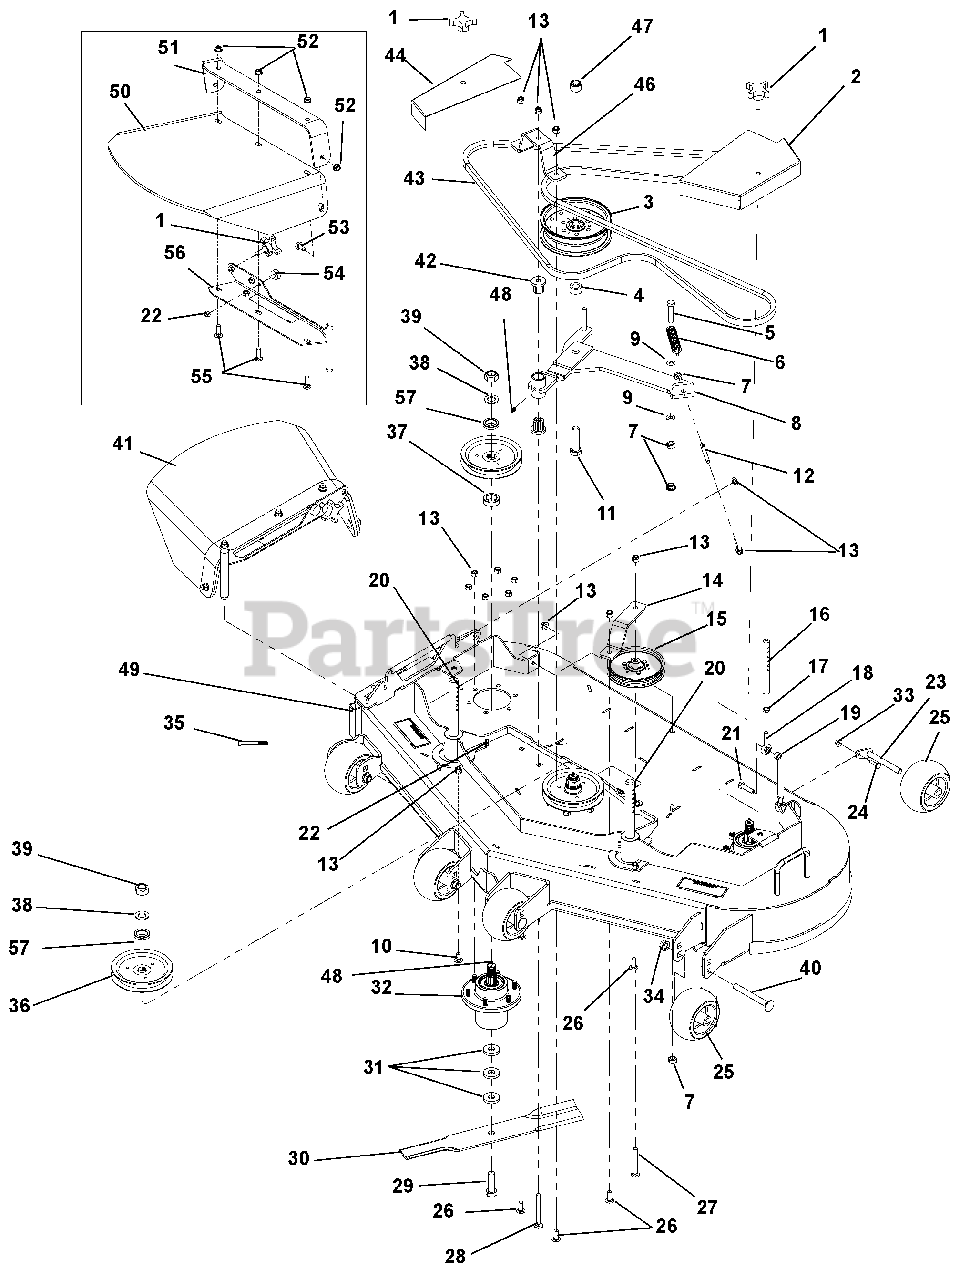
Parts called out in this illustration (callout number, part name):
1	KNOB, .38 x 1.25- 4 PRONG (SN 000101 - 020000
2	SHIELD, LH SPINDLE 52 FLWLK (988155, 158)
3	PULLEY, FLAT 6.00 X .635 W/BRG
4	BUSHING, .688 X 1.13 X .55
5	BLT-HEX .38-16X1.75 GR5 YWZC
6	SPRING, EXT .875 X .125 X 4.25 Y
7	NUT, SPNLK-FLG .375-16
8	WLDT, IDLER ARM 48/52 FLOAT WALK
9	WASHER, FL-STL .406 X .812 X .065
10	BOLT, RDHDSHSQNK .38-16 X .75 G5
11	BOLT, HEX .62-11X2.50 GR5Y
12	ROD, THREADED ADJUSTMENT
13	NUT-LK-NYL .38-16
14	STRAP, IDLER 52/48 WALK
15	PULLEY, FLAT 5.00X.375 W/BRG
16	ROD, REAR HOC
17	NUT, JAM .375-24 YWZC REV
18	ROD, END 3/8 RH REV
19	BSHG - SLV REV
20	PIN, HOC
21	BLT-HEX .38-16X1.75 GR5 YWZC
22	NUT-SPNLK-FLG .312-18
23	PIVOT, RETAINER WELD
24	BOLT, RDHDSQNK .25-20 X 1.00 G5
25	ANTI-SCALP WHEEL - 5X3 CTR
26	BOLT, RDHDSQNK .38-16 X 1.00 G5
27	BOLT, RDHD SQNK .38-16 X 3.0 GR5YZ REV
28	BOLT, RDHDSQNK .38-16 X 3.50 GR5
29	BOLT, .62-11 X 2.00 HEX 8 Y
30	BLADE, 18.000 X .80 LIFT (988155, 158)
31	WASHER, FL-STL .630 X 1.50 X .25
32	ASSY, SPINDLE S/O
33	NUT, LK-NYL-FLG .25-20
34	NUT-LK-NYL-FLG .50-13
35	BOLT, 5/16-18 X 2.50 HEX 8
36	PULLEY, SPLINE SPINDLE SHFLWLK (SN 000101 - 020000)
37	SPACER, 1.500 X 1.000 X .510 Y (SN 000101 - 020000)
38	WASHER, .75 X 1.3125X .113
39	LOCKNUT, 3/4-16 CROWN GR 5
40	BOLT, RDHDSQNK .50-13 X 4.50 G5
41	ASSY, DISCHARGE SHIELD
42	BRG, FLG M10 X M25 X M27 FLUTED
43	BELT, HB 131.0 EL AMD (988155, 158)
44	SHIELD, RH SPINDLE 52 FLWLK (988155, 158)
45	SHIELD, LH SPINDLE 48 FLWLK (988154, 157)
46	STRAP, IDLER 52 FLOAT WALK (988155, 158)
47	NUT, LK-NYL .625-11 YWZC REV
48	FTG, 1/4-28 STRGT GREASE ZERK
49	ASSY, 52" FLOAT DECK W/DECALS (988155, 158)
50	SHIELD, WALK RUBBER DISCHARGE
51	STRAP, GRAVELY WLK RUBBER DIS
52	NUT, SPNLK-FLG .375-16
53	BOLT, RDHDSQNK .38-16 X 1.00 G5
54	BUMPER, RUBBER
55	BOLT, RDHDSQNK .38-16 X 1.25 G5
56	WLDT. DISCHARGE
57	WSHR-FL-STL 1.0X1.50X.25 (SN 020001 and up)
